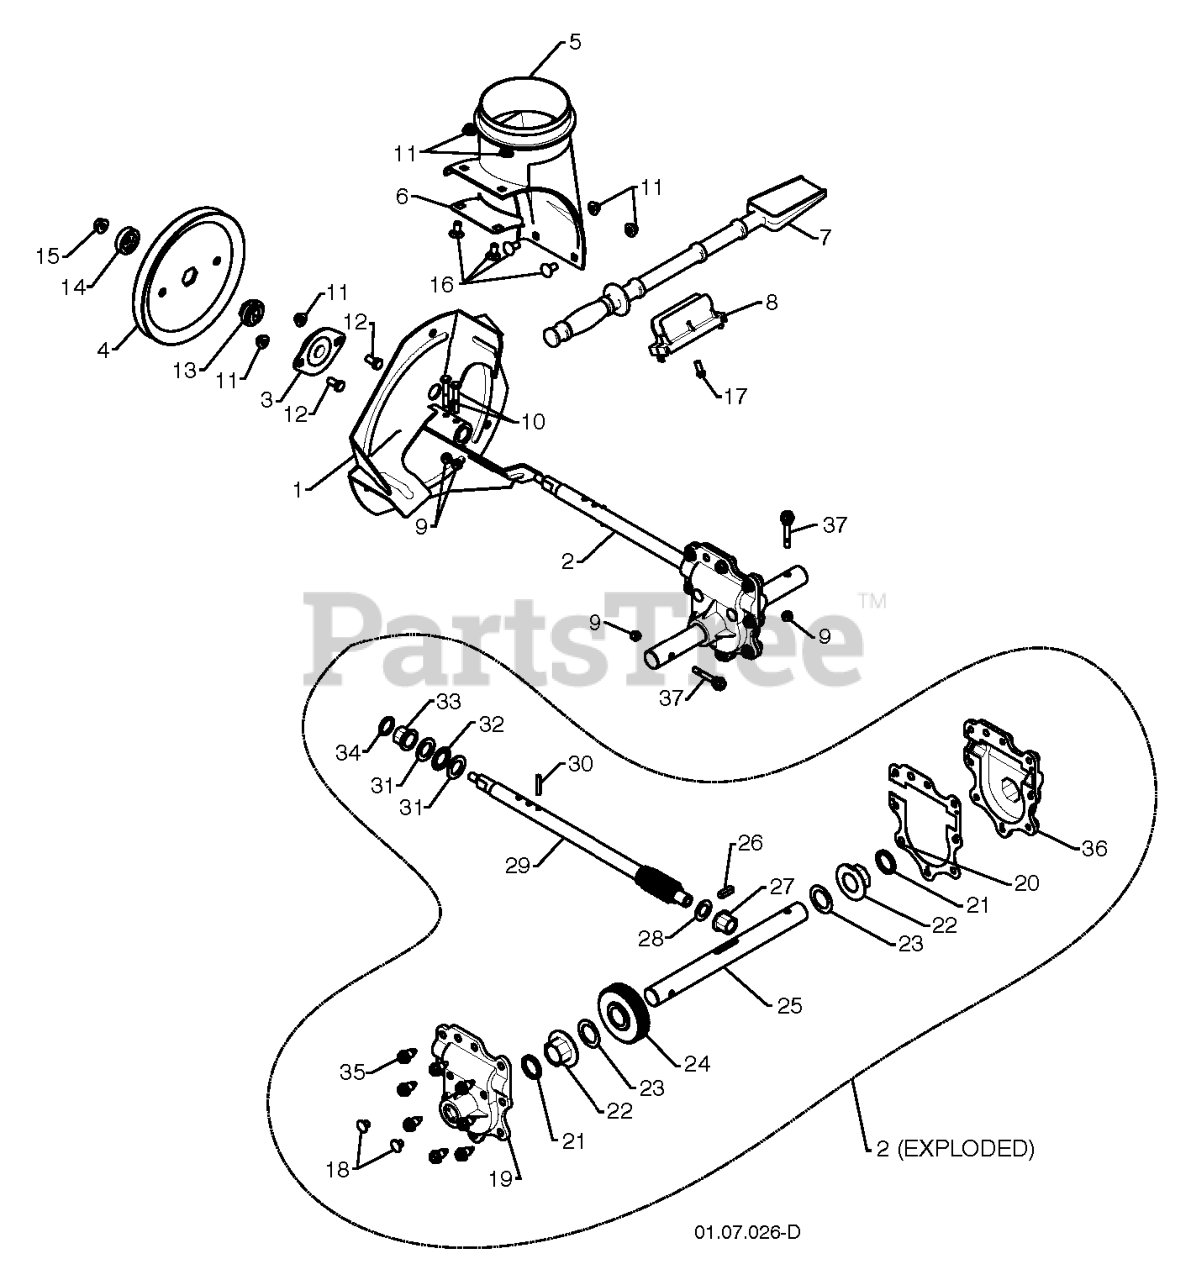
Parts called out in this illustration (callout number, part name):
1	IMPELLER.WELDMENT.BLACK
2	GEARBOX.ASM.AUGER.D-SHAFT
3	BEARING FLANGE
4	PULLEY.FLANGE.IMPELLER
5	BASE DISCHARGE CHUTE
6	BRACKET.CORNER.DISCHARGE
7	CLEAN OUT TOOL
8	CLIP.CLEANOUT.TOOL
9	LOCKNUT.NYLOC.1/4-20
10	SCREW.HEX.HD1/4-20X
11	NUTNYLOK.FLRANGE.5/16-18
12	BOLT, HEX HEAD 5/16-18
13	HUB.IMP.PULLEY.D-SHAFT
14	SLEEVE.IMP.PULLEY.D-SHAFT
15	NUT LOCK FLG 3/8-16 UNC
16	BOLT.CARRIAGE.5/16-18X
17	SCREW.HWH.13-16-5.8.BZP
18	CASE PLUG
19	GEAR.BOX.COVER.RIGHT.SIDE
20	GASKET.GEAR.BOX
21	OIL SEAL
22	FLANGE BUSHING-1"
23	WASHER TRUST 1"
24	WORM GEAR
25	AUGER SHAFT
26	KEY, SQUARE 1/4 X .875
27	FLANGE BUSHING-5/8
28	WASHER, THRUST 5/8
29	SHAFT.IMPELLER.D-SHAFT
30	PIN, ROLL 3/16 X 1-1/8
31	WASHER, THRUST 3/4
32	BEARING TRUST 3/4 NTA-1220
33	BUSHING, FLANGE 3/4
35	HEX SCREW-5/16 X 3/4
36	GEAR.BOX.COVER.LEFT.SIDE
37	BOLT.SHOULDER.SHEAR.1/4-20.
